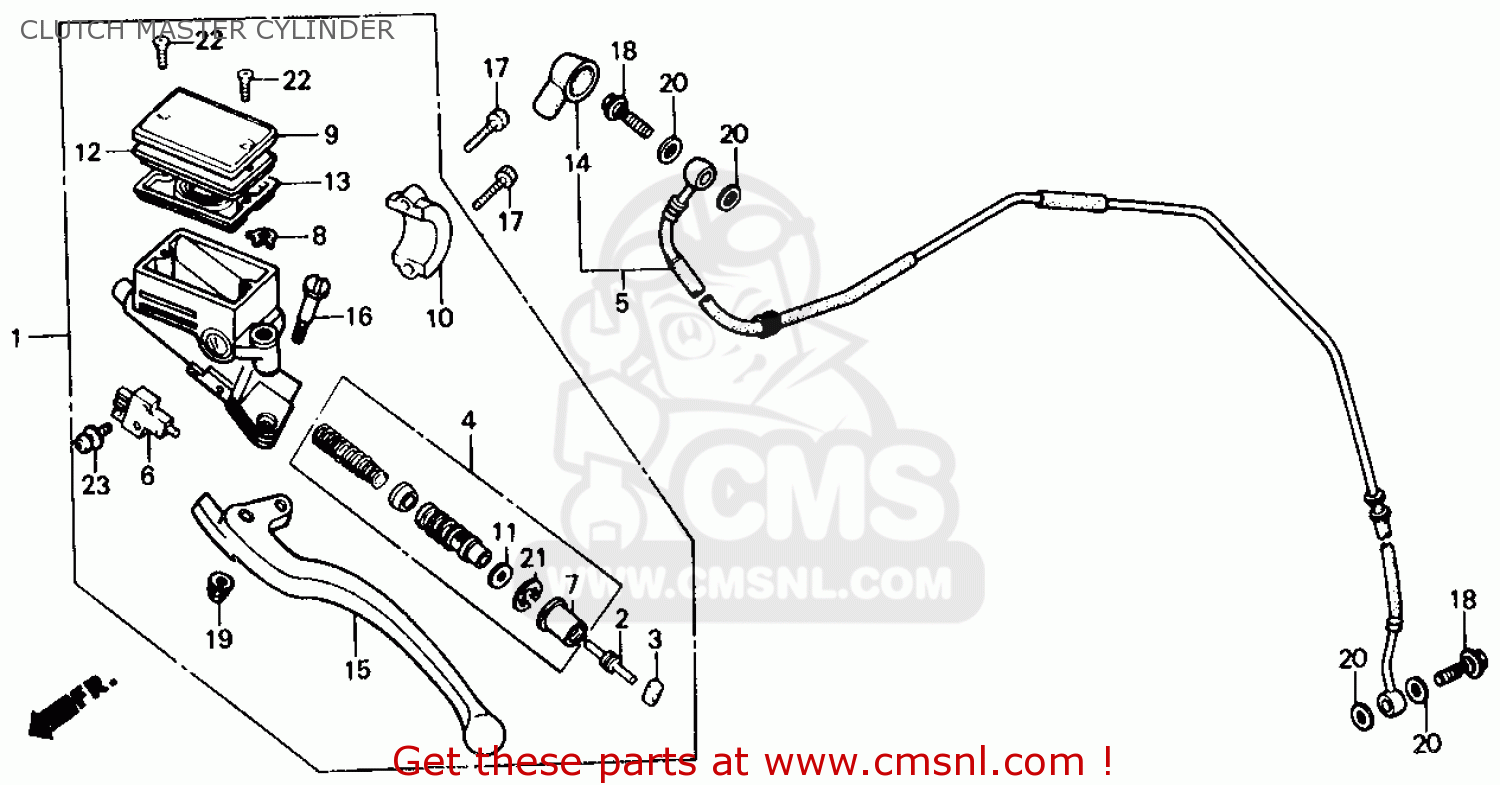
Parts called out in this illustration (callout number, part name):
1	CYLIN,FR.CLCH.MAS
2	ROD,PUSH
3	BUSH
4	PISTON SET,CLUTCH
5	PIPE COMP.,CLUTCH
6	SW.ASSY.,CLUTCH
7	BOOT COMP.
8	PROTECTOR
9	CAP,MAS.CYLINDER
10	HOLDER,MASTER.CYL
11	PLATE,STOPPER
12	PLATE,DIAPHRAGM
13	DIAPHRAGH
14	BOOT,MASTER CYLN.
15	LEVER,L.HANDLE
16	BOLT,HNDL PIVOT
17	BOLT,SOCKET,6X23
18	BOLT,OIL,10X22
19	NUT,CAP,6MM
21	CIR CLIP,INTERNAL
22	SCREW,FLAT,4X12
23	SCREW-WASH,4X12
